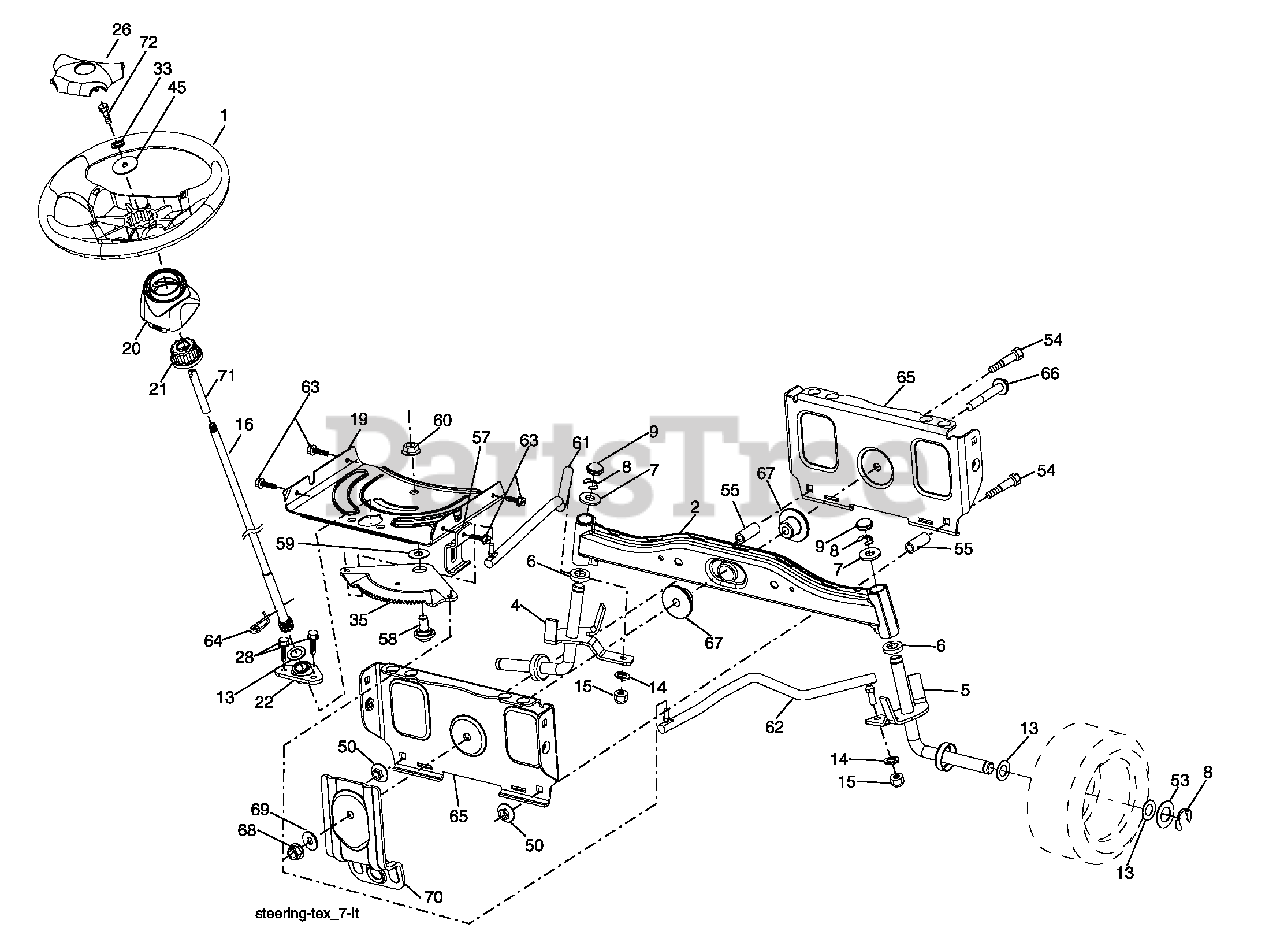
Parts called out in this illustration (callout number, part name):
1	Wheel, Steering
2	Axle Asm., Front
4	Spindle Asm., LH
5	Spindle Asm., RH
6	Bearing, Race Thrust Harden
7	Washer 25/32 x 1-5/8 x 16 Ga.
8	Ring, Klip #T5304-75
9	Cap, Spindle
13	Washer 25/32 x 1-1/4 x 16 Ga.
14	Washer, Lock Hvy Hlcl Spr 3/8
15	Nut, Crown Lock 3/8-24 unf
16	Shaft Steering
19	Plate Steering
20	Boot, Steering
21	Adapter, Wheel Steering
22	Bushing, Strg. Blk
26	Insert, Wheel Steering
28	Screw 3/8-16 x 3/4
33	Washer Lock 5/16
35	Gear, Sector Plate
45	Washer 11/32 ID x 2-3/8 x 12 Ga.
50	Nut Lock 3/8-16
53	Washer Hardened .793 x 1.637 x .060
54	Bolt 3/8-16 x 2-1/4
55	Spacer Brace Axle
57	Bracket Upstop
58	Bolt Shoulder Sector Pivot CFM
59	Washer Thrust Sector Steering
60	Nut Flange Lock 5/8-11
61	Draglink LH
62	Draglink, RH
63	Screw 5/16-18 x 3/4
64	Retainer Clip Spring Steering
66	Bolt Hex Fghd 7/16-14 x 3 Serr
67	Bushing PM Front Axle
68	Nut Lock Flange 7/16-14 Gr. 5
69	Washer 1.5 x .505 x .118
70	Bracket Deck Susp. Front
71	Shaft Exten Strg.
72	Bolt Fin Hex 5/16-18 UNC x 4.5 G5
